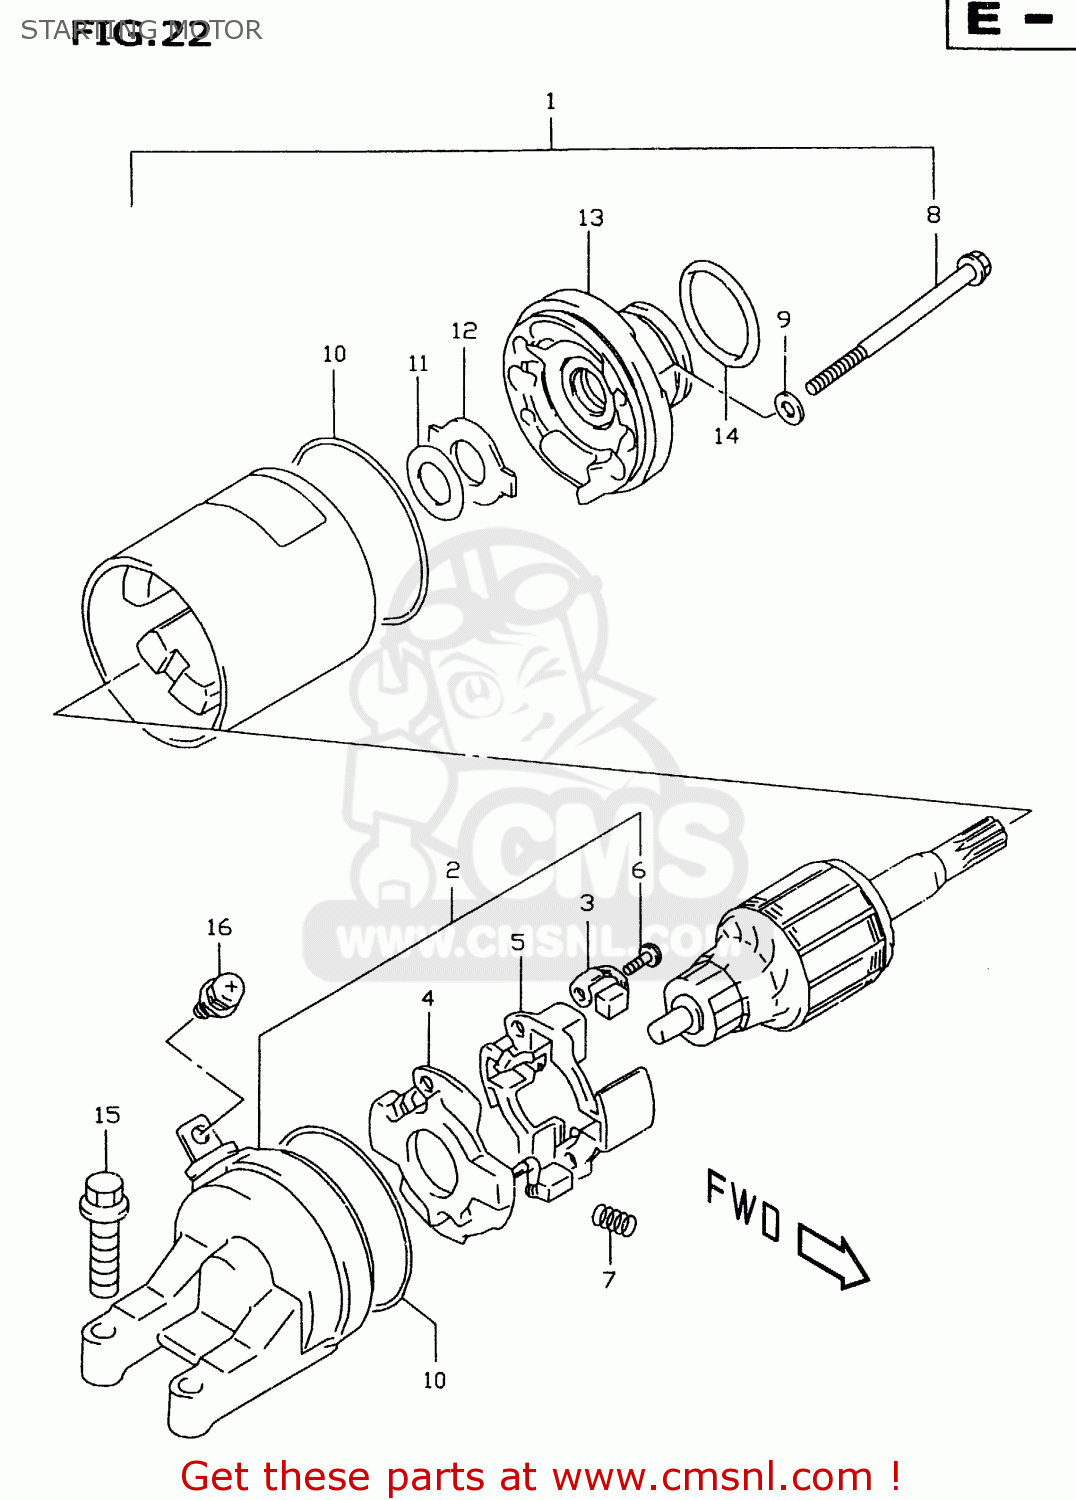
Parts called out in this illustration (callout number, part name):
1	MOTOR ASSEMBLY,STARTING
2	FRAME ASSEMBLY,COMMUTATOR
3	BRUSH
4	BRUSH SUB ASSY,STARTER
5	HOLDER,BRUSH
6	SCREW
7	SPRING
8	BOLT
9	O RING
10	O RING
11	SHIM
12	PLATE,LOCK
13	BRACKET
14	O RING(D:3,ID:24.5)
15	BOLT(6X20)
16	SCREW(5X8)
